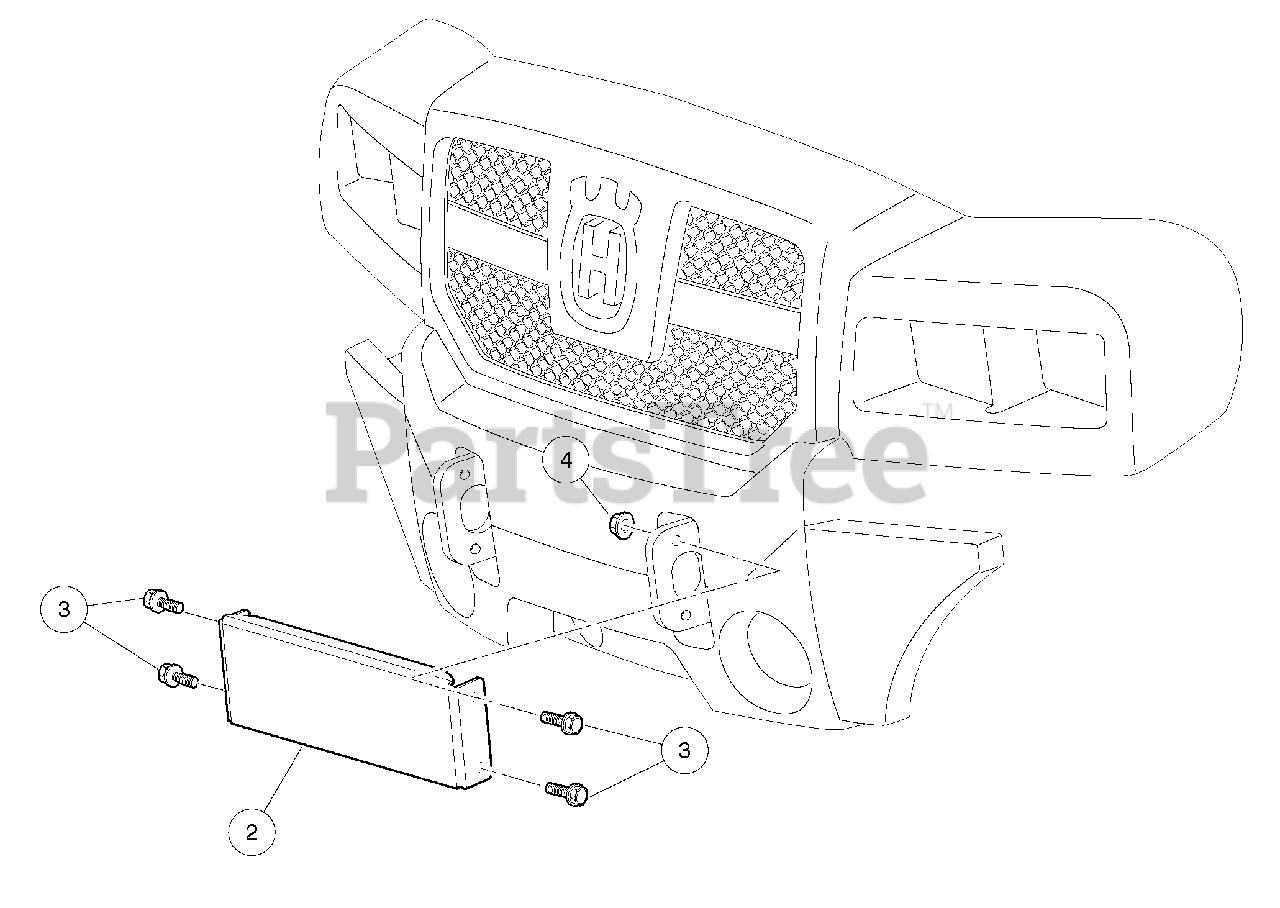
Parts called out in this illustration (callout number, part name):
1	Instl, Bumper Plate, Huv
2	Bumper Plate, Huv
3	Screw, M10 X 1.25 X 30 Hex Blk
4	Nut, Flg, M10 X 1.25 Hex Blk
